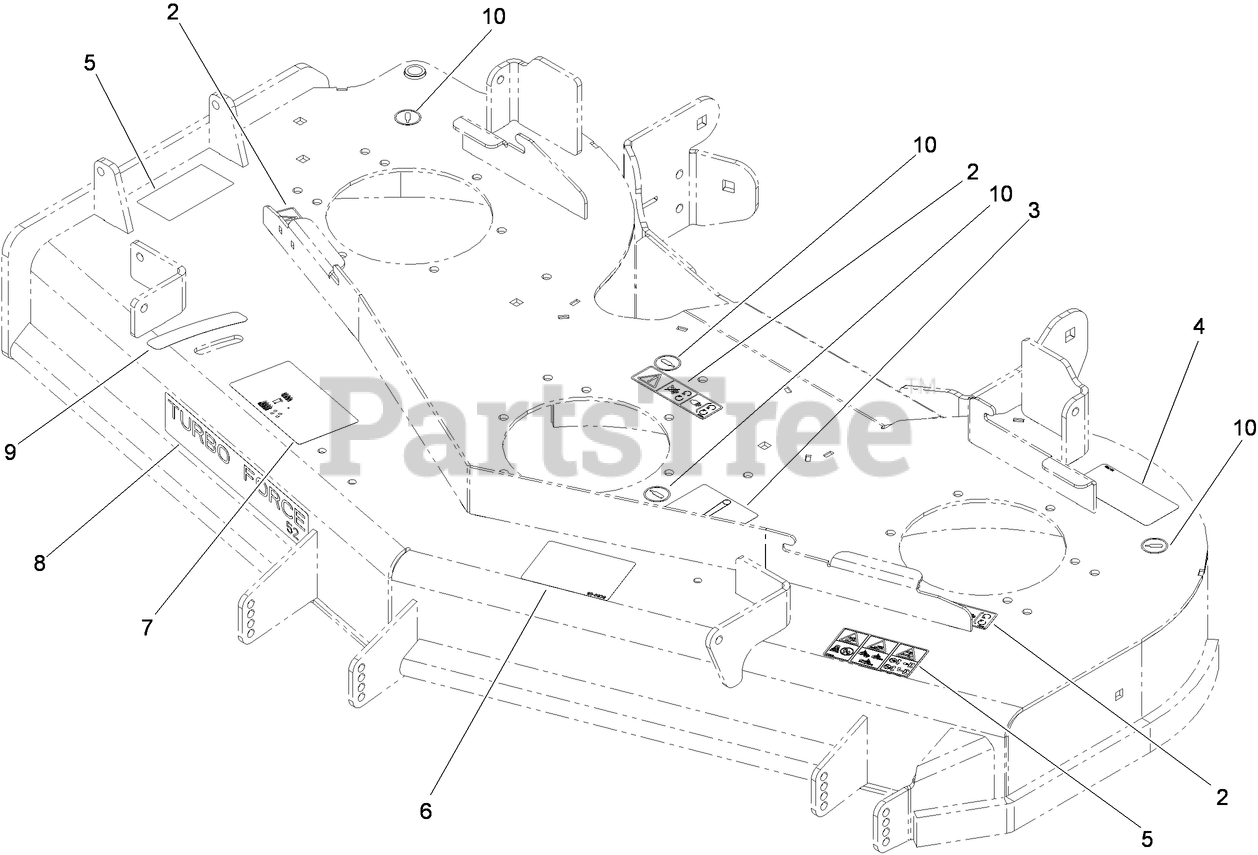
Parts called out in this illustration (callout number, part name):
2	DECAL-MISSING, COVER
3	DECAL-ROUTING, DECK BELT
4	DECAL-TORQUE, BLADE BOLT
5	DECAL-DANGER
6	DECAL-ANTI SCALP
7	DECAL-ADJUSTMENT, BAFFLE
9	DECAL-SETTING, BAFFLE
10	DECAL-GREASE
